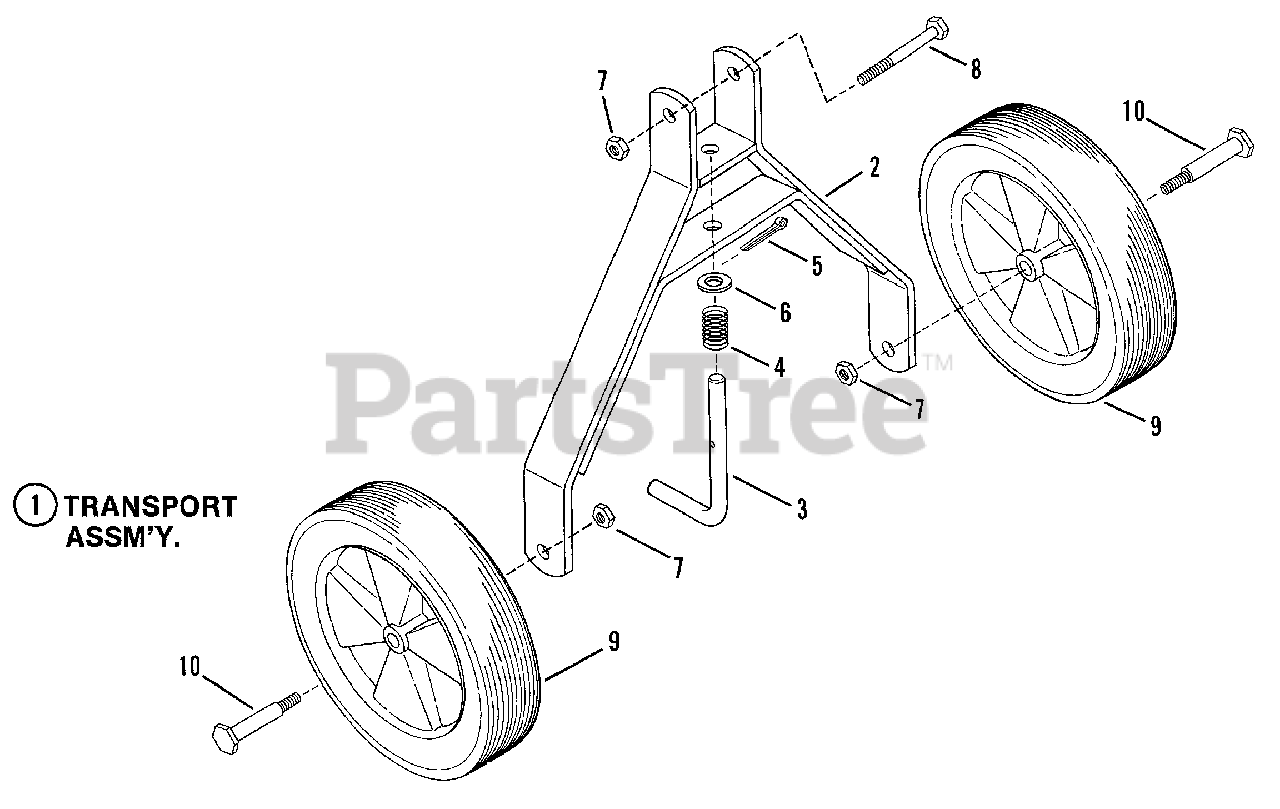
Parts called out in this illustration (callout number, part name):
1	TRANSPORT ASSM'Y.
2	FRAME, Arm-Wheel Structure
3	PIN, Wheel Arm Lock
4	SPRING, Lock Pin
5	PIN, 1/8x1-1/4" Cotter
6	WASHER, 1/2 SAE
7	NUT, 3/8-24 Hex Lock
8	SCREW, 3/8-24x2-3/4" Hex Hd. Cap
9	WHEEL, 10"x1-3/4"
10	BOLT, 3/8-24x2-5/16" Shoulder
